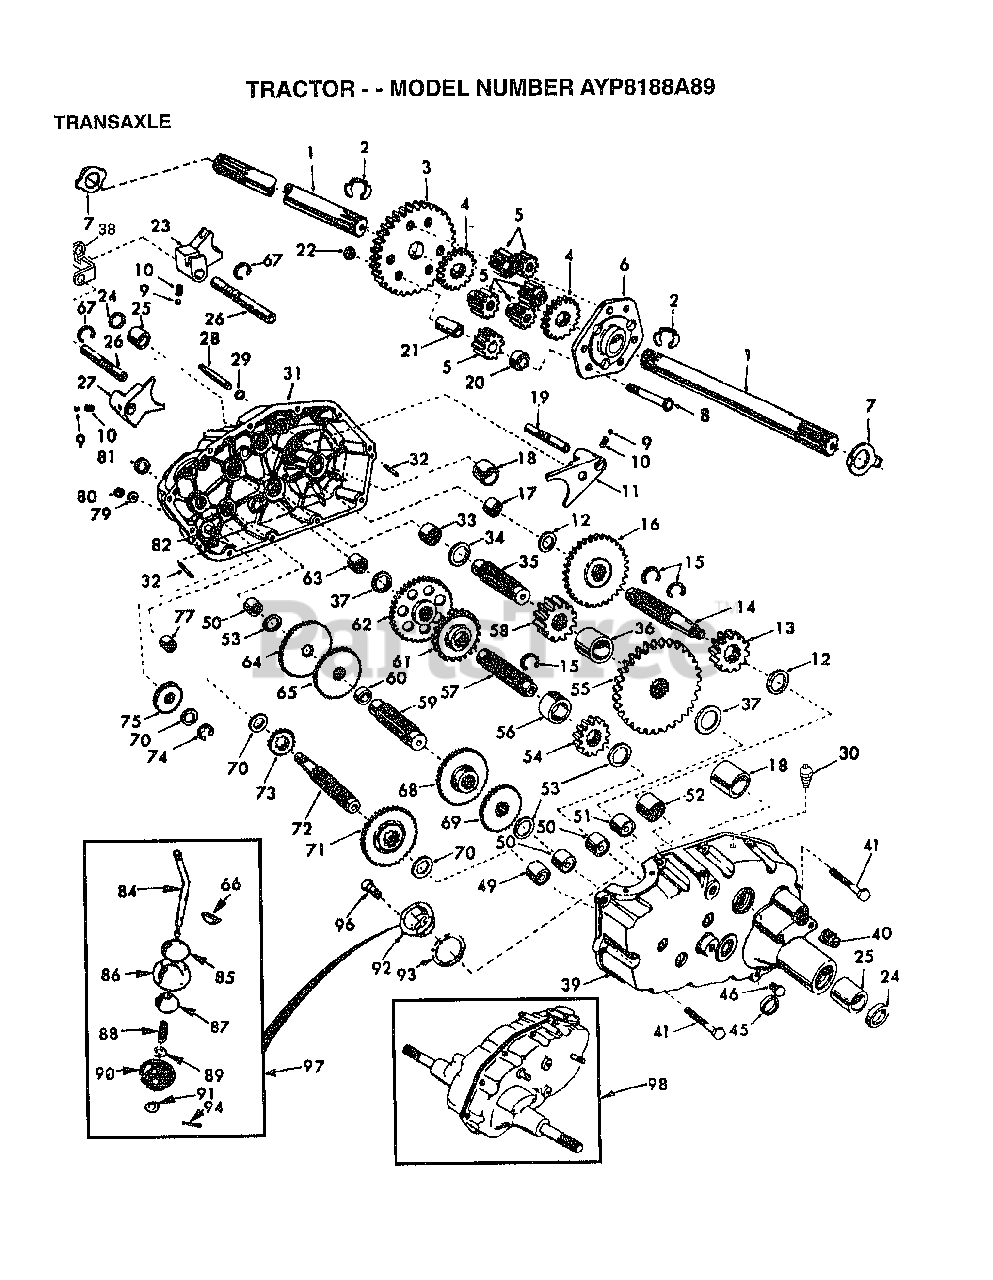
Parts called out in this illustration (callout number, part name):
1	SHAFT.AXLE.T
2	KLIP RING
3	FINAL GEAR T
4	DIFF GEAR T
5	DIFF PINION T
6	DIFF CARRIER T
8	BOLT
11	SHIFT FORK T
13	RED PINION T
14	SHAFT BRAKE GT
15	SNAP RING T
16	GEAR T
17	"T, BEARING"
18	BEARING
19	SHAFT
20	SPACER T
21	PINION RS
22	GRIPCO NUT
23	FORK T
24	OIL SEAL STD
25	BRNG. T
26	SHIFT FORK SHAFT
27	SHIFT FORK T
28	SHIFT SHAFT
29	SEAL T
30	VALVE M
31	GEARCASE RH W/BER
32	PIN T
33	NEEDLE BRNG T
34	RACE T
35	GEAR SHAFT T
37	RACE T
38	GAT.LOWE.SHIFT.VGT
39	GEARCASE LH W/BER
40	PLUG PIPE
41	BOLT.5/16-18X1.25
45	SEAL T
49	"TI, BEARING"
50	NEEDLE BRNG T
51	NEEDLE BRNG T
52	"STD, BEARING"
53	BRNG RACE
54	RED PINION T
55	RED GEAR T
56	PINION SPACER T
57	GEAR SHAFT T
58	FINAL PINION T
59	GEAR SHAFT T
60	SPACER T
61	RED PINION T
62	RED GEAR T
63	RACE T
64	LOW SPEED GEA T
65	REVERSE GEAR T
66	KEY T
67	KLIP RING
68	INTERMED GEAR T
70	"T, BEARING"
71	CLUSTER GEAR T
72	SHAFT INPUT
73	LO SPEED PINION T
74	KLIP RING
75	IDLER GEAR T
77	NEEDLE BEARING TI
79	WASHER T
80	NUT
81	SEAL STD
82	SHAFT REVERSE IDL
84	GEAR SHIFT LVR T
85	CAP T
86	COVER AND PIN T
87	GUIDE BALL T
88	SPRING TI
89	WASHER
90	SEAL T
91	WASHER
92	GEAR SHIFT GA T
93	GASKET T
94	COTTER PIN
96	SCREW.HX.W.HD.MAC
97	GEAR SHFT LVR T
98	TRANSAXLE ASM 6SP
99	GAT.LOWE.SHIFT.VGT
